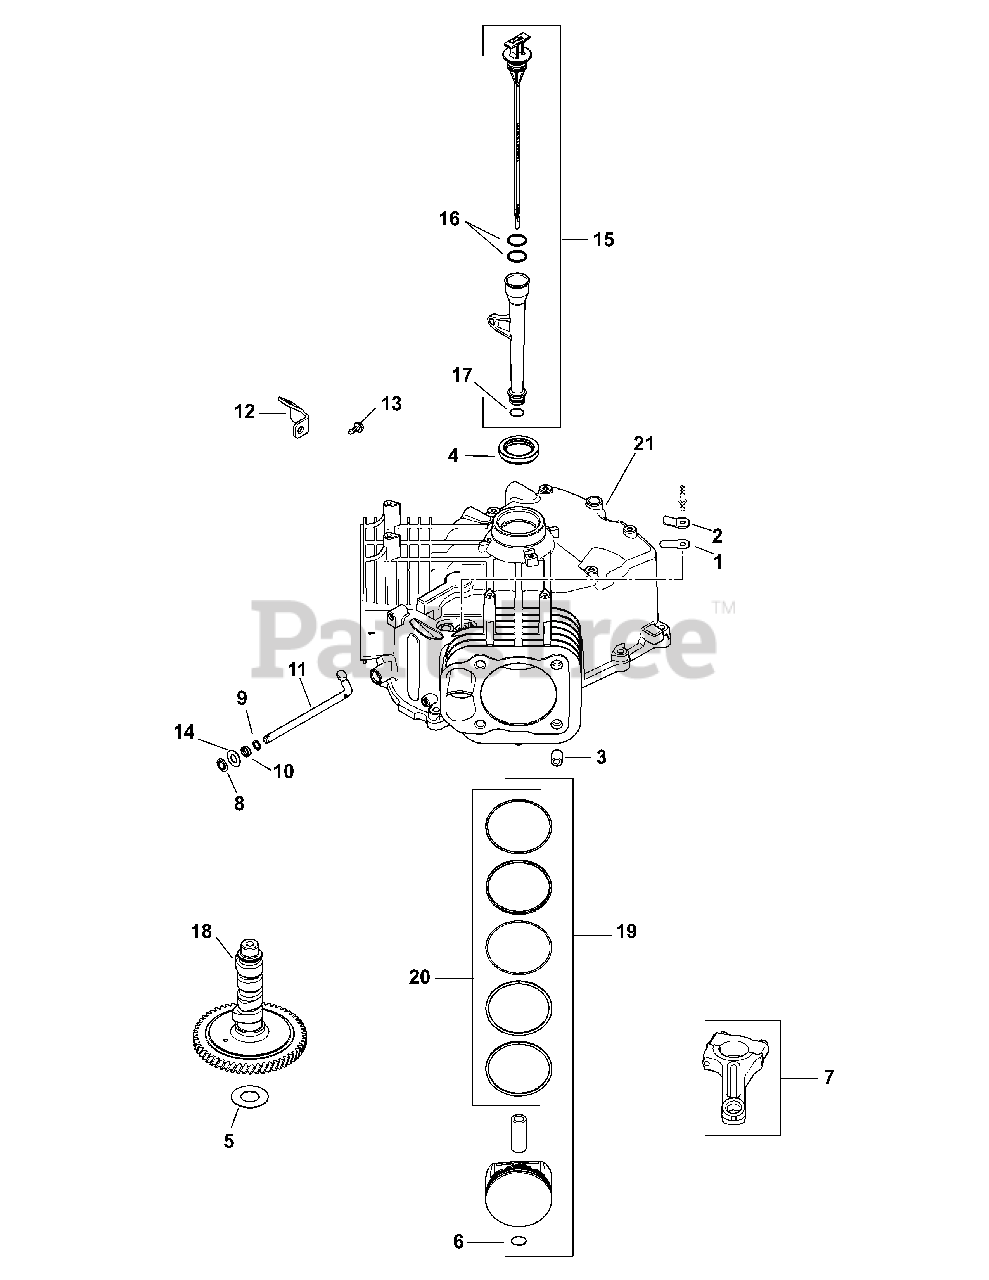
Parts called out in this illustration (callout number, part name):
1	Breather Reed
2	Breather Reed Retainer
4	Oil Seal, 1.78 x 1.26
5	Camshaft Shim (White, .028)
5	Camshaft Shim (Blue, .03)
5	Camshaft Shim (Red, .032)
5	Camshaft Shim (Yellow, .034)
5	Camshaft Shim (Green, .036)
5	Camshaft Shim (Gray, .038)
5	Camshaft Shim (Black, .04)
6	Piston Pin Retainer
7	Connecting Rod (STD)
8	Ring Retainer
9	Flat Washer, 11/32
10	Governor Cross Shaft Seal
11	Governor Cross Shaft
12	Oil Fill Tube Bracket
13	Flange Screw, M5 x .8 x 13
14	Flat Washer, 9mm
15	Dipstick & Tube Kit
17	Lower Oil Fill Tube O-Ring
18	Camshaft Assembly
19	Piston Kit w/ Ring
19	Piston Kit w/ Ring (0.25) 83mm
19	Piston Kit w/ Ring (0.08) 83mm
20	Ring Set, Piston STD
20	Ring Set, Piston (.08)
20	Ring Set, Piston (.25)
21	Crankcase (Use Short Block)
